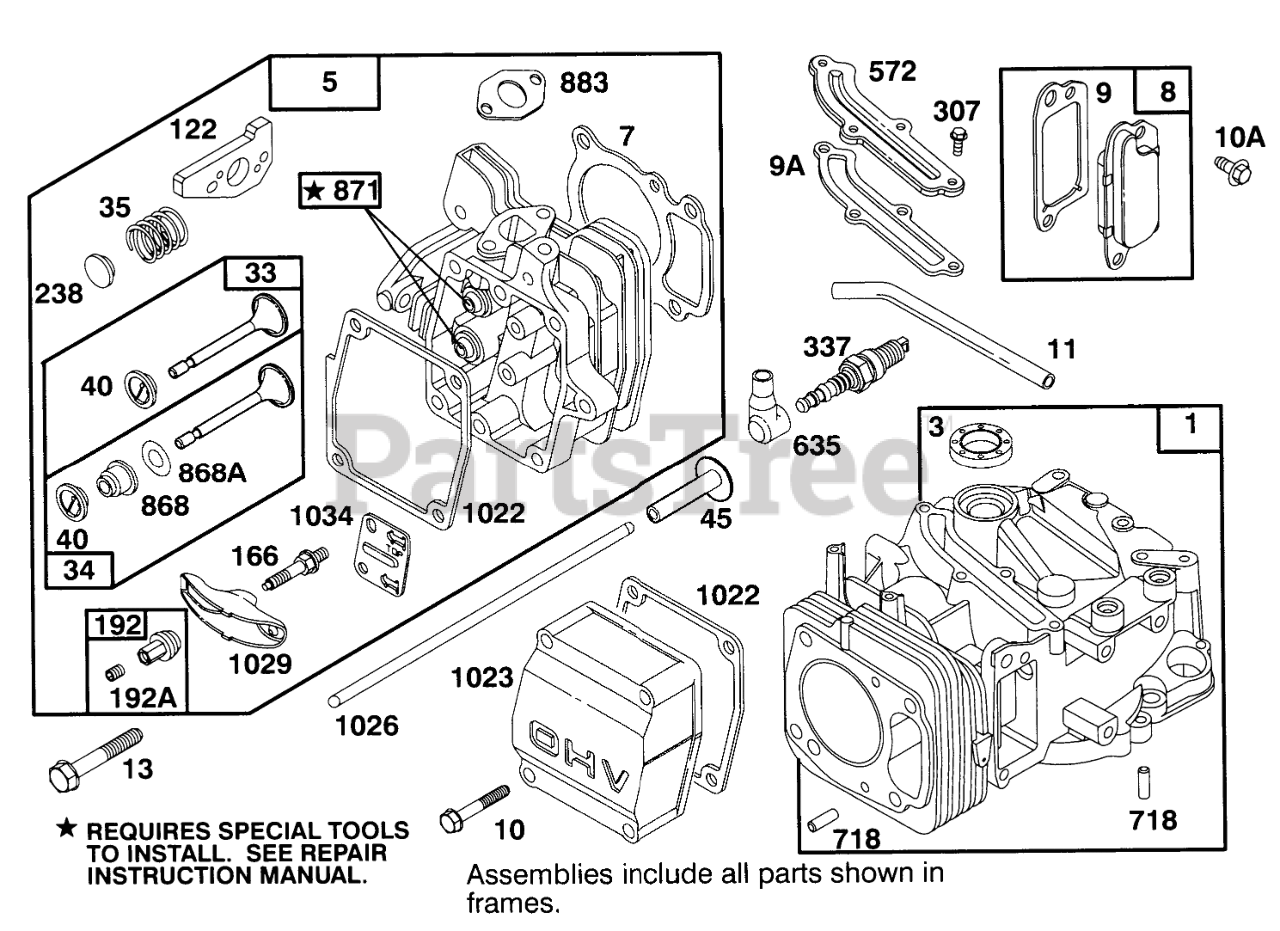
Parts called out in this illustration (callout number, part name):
1	CYLINDER ASSEMBLY
3	SEAL - OIL
5	CYLINDER HEAD
7	CYLINDER HEAD GASKET
8	Breather Assy
9	BREATHER GASKET
9A	GASKET-BREATHER
10	HEX HEAD SCREW
10A	HEX HEAD SCREW
11	TUBE - BREATHER
13	CYLINDER HEAD SCREW
33	EXHAUST VALVE
34	INTAKE VALVE
35	VALVE SPRING
40	SPRING RETAINER
45	VALVE TAPPET
122	ADAPTER ASSEMBLY
166	ROCKER ARM STUD
192	NUT - HEX SPECIAL
192A	SCREW SET
238	VALVE CAP
307	SCREW - SEM
337	PLUG-SPARK
572	BAFFLE - CYCLINDER
635	SPARK PLUG ELBOW
718	DOWEL - SLEEVE
868	SealAssy-Valve
868A	Seal-Valve
871	Bushing-Guide
883	EXHAUST GASKET
1022	ROCKER COVER GASKET
1023	COVER - VALVE
1026	PUSH ROD
1029	ROCKER ARM
1034	PUSH ROD GUIDE
